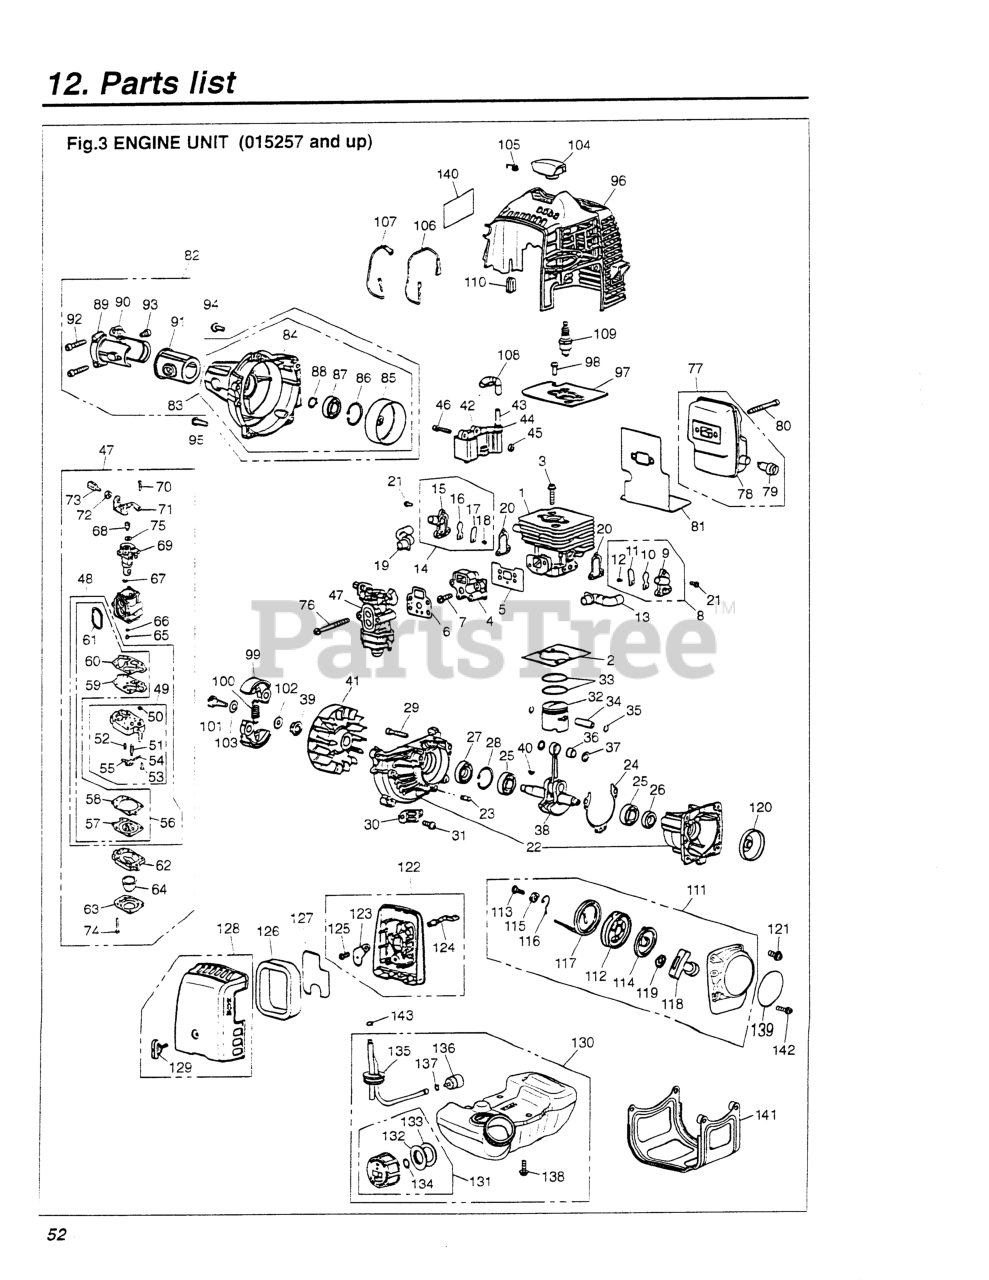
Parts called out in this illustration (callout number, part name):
1	CYLINDER (RPLS -12110)
2	GASKET, BASE
3	BOLT, M5 X 22
4	INSULATOR (RPLS. -13160/13161)
5	GASKET, INSULATOR
6	GASKET, CARBURETOR
7	SCREW, M5X20 (RPLS.1400-75510)
9	CASE VALVE
10	VALVE, REED
11	STOPPER
12	SCREW, M3 x 8
13	PIPE, AIR
16	VALVE, REED
17	STOPPER
18	SCREW, M3 x 8
19	PIPE, AIR (F)
20	GASKET, VALVE
21	SCREW
22	CRANKCASE COMP (USE 4810-21101
23	PIN
24	GASKET
25	BEARING
26	SEAL
27	SEAL, OIL (RPLS 1140-21220)
28	RING, SNAP, M28 x 1.2
29	BOLT, M5 X 30
31	SCREW, M5 X 10
32	PISTON
33	RING, PISTON
34	PIN, PISTON
35	RING, SNAP (RPLS 1101-41320)
36	BEARING (RPLS 1140-41330)
37	WASHER
38	CRANKSHAFT COMPLETE
40	KEY
41	ROTOR
42	COIL-A
43	CORD
44	CAP
45	SPACER (RPLS -71260)
46	BOLT, M4 x 22
49	PUMP BODY ASSEMBLY
50	SCREEN
51	VALVE, INLET
53	SCREW
54	PIN
55	LEVER
57	DIAPHRAGM
58	GASKET, DIAPHRAGM
59	DIAPHRAGM, PUMP
60	GASKET, PUMP
61	RING
62	BODY, PURGE
63	COVER, PUMP
64	PUMP, PRIMING
65	JET (REPLACES 4810-81250)
66	RING, O
67	RING
68	SWIVEL
69	VALVE ASSY
70	SCREW
72	NUT, CABLE ADJUSTER
73	SCREW, CABLE ADJUSTER
74	SCREW
75	WASHER
76	SCREW, M5 x 60
77	MUFFLER ASSEMBLY
78	MUFFLER (REPLACES -15110)
79	ARRESTER
80	BOLT, M5 x 50
84	COVER, FAN (USE -31111)
86	RING, SNAP, M28 x 1.2
87	BEARING
88	RING, SNAP (RPLS 3130-13270)
89	BRACKET (A) (RPLS -31210)
90	BRACKET (B) (REPLACES -31220)
91	CUSHION
92	BOLT, M5 X 30
93	BOLT (USE 3310-31720)
94	SCREW
95	SCREW, M5X20 (RPLS.1400-75510)
96	COVER, ENGINE (RPLS -32110)
97	PLATE
98	SCREW, M5 X 10
99	SHOE (RPLS 1100-51114)
100	SPRING
101	BOLT
102	WASHER, FLAT (USE 182303)
105	SPRING
106	CORD (BLACK)
107	CORD, EARTH (RED)
110	GROMMET
111	RECOIL ASSEMBLY
112	REEL
113	SCREW
114	SPRING, SPIRAL
115	COLLAR
116	ARM
117	ROPE (REPLACES 4500-75160)
118	KNOB (RPLS -75420)
119	PLATE, STOPPER
120	PULLEY
121	SCREW
122	BODY ASSEMBLY
123	PLATE, CHOKE
124	LEVER, CHOKE
125	SCREW (REPLACES 50030272)
126	ELEMENT
127	SCREEN
128	COVER ASSEMBLY
129	KNOB (RPLS -82220)
132	HOLDER (REPLACES -85230)
133	PACKING
134	FILTER
135	PIPE COMPLETE
136	FILTER (RPLS 1850-85300)
137	CLIP (REPLACES 2841-31280)
138	SCREW
139	LABEL, RECOIL
140	LABEL, COVER (RPLS -31130)
142	SCREW, M5 x 25
143	CLIP
